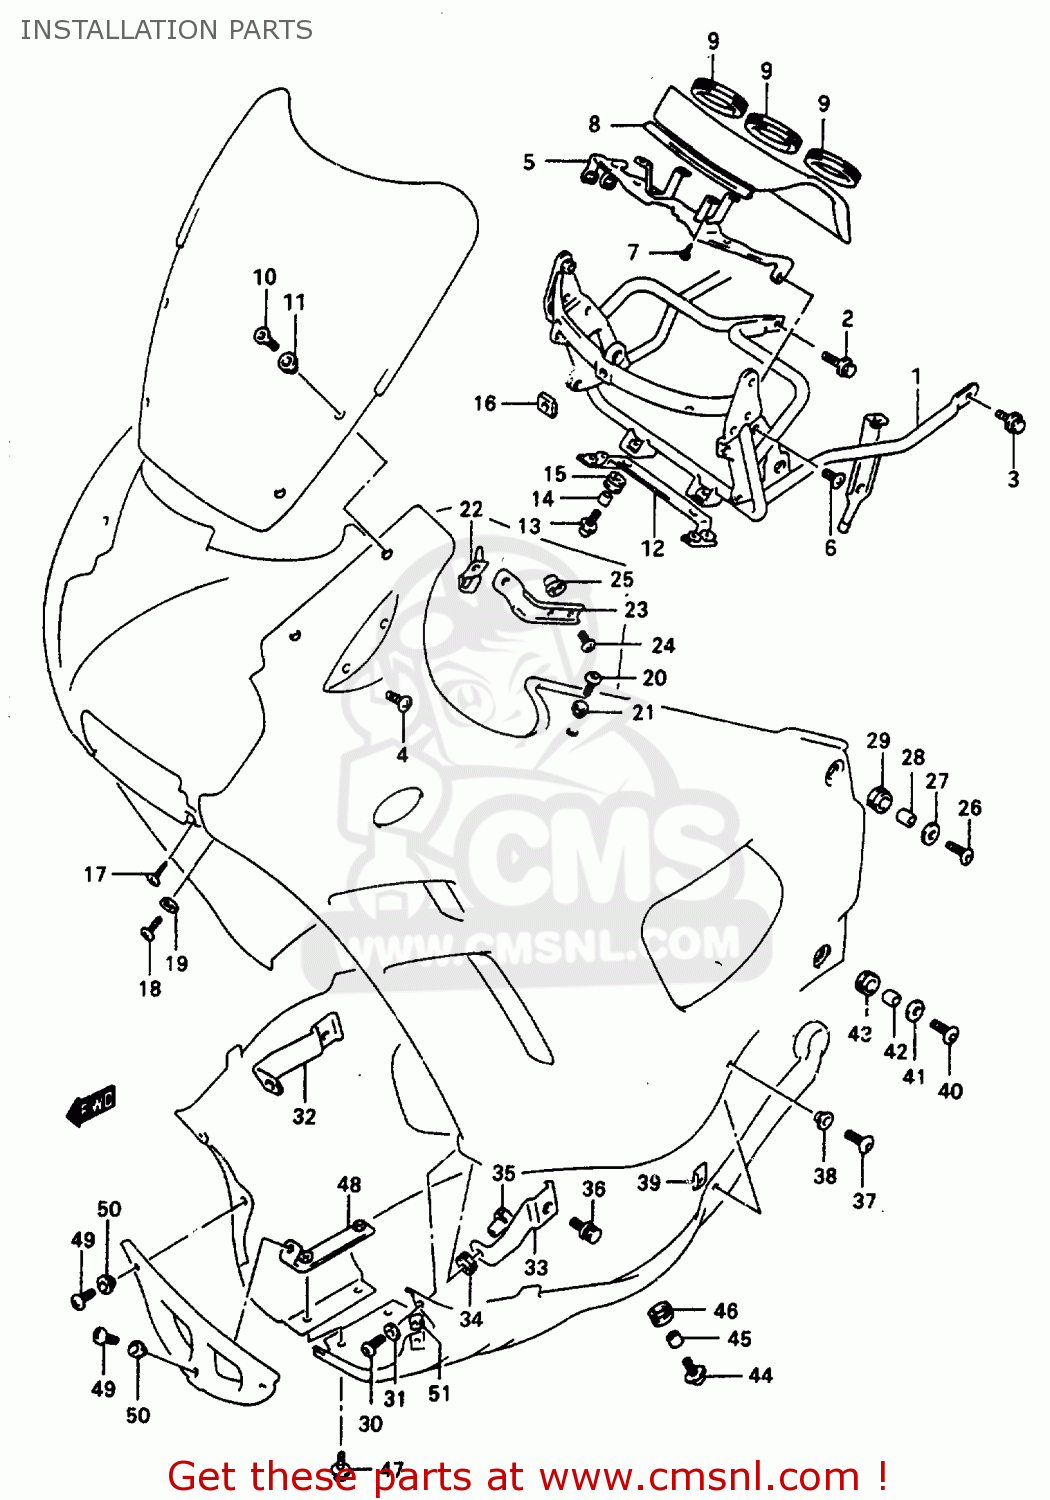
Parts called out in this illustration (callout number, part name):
1	BRACE,COWLING
2	BOLT(8X20)
3	BOLT
4	SCREW 6X12
5	PLATE,METER FITING
6	SCREW 6X12
7	SCREW 5X8
8	MOLDING,METER COVER
9	CUSHION,METER COVER
10	SCREW
11	WASHER
12	PLATE,COWL CTR PANEL
13	SCREW(6X20)
14	SPACER (6.5X10X9.4)
15	CUSHION
16	CUSHION,SCREEN
17	SCREW 5X12
18	SCREW(6X25)
19	WASHER
20	SCREW(6X16)
21	WASHER(6.3X16X1.5)
22	BRACKET,COWLING UPR,R
23	BRACKET,COWLING UPR,L
24	SCREW
25	NUT,COWLING SIDE BRKT
26	SCREW(6X25)
27	WASHER
28	SPACER(6.5X9X9)
29	CUSHION
30	SCREW(6X30)
31	WASHER
32	BRACKET,COWLING LWR,R
33	BRACKET,COWLING LWR,L
34	CUSHION
35	NUT,COWLING,FR
36	BOLT
37	SCREW(5X14)
38	WASHER(5.2X14X1.5)
39	NUT,HEADLAMP HOUSING,UPPER
40	SCREW(6X25)
41	WASHER
42	SPACER(6.1X9X12.3)
43	CUSHION
44	SCREW(6X20)
45	SPACER(6.5X9X9)
46	CUSHION
47	SCREW
48	BRACKET,FR UNDER COWL
49	SCREW
50	WASHER(5.2X14X1.5)
51	NUT,HEADLAMP HOUSING,UPPER
